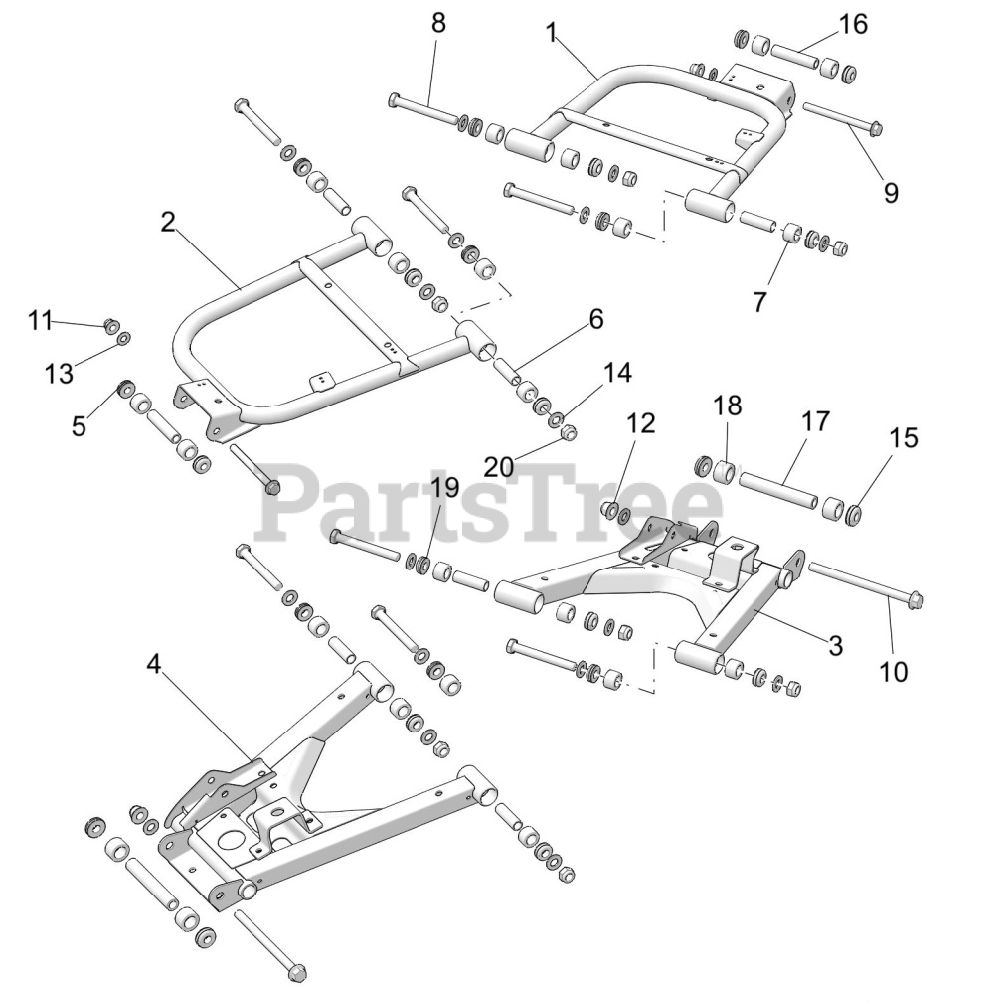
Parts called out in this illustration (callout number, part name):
1	WELD-CONTROL ARM, RR, UPR, LH, BLK
2	WELD-CONTROL ARM-RR-UPR-LH-BLK
3	WELD-CONTROL ARM-RR-UPR-RH-BLK
4	WELD-CONTROL ARM-RR-LWR-LH-BLK
5	WELD-CONTROL ARM-RR-LWR-RH-BLK
6	ASM-PIVOT CAP- SEALED- M10
6	SHAFT-PIVOT-SHORT-M12
8	BUSHING-STANDARD-SUSP-M10
9	SCR-HH-M12X1.75X100 10.9 ZPC
10	SCR-HXFL-M10X1.25X115 10.9 SPC
11	SCR-HXFL-M12X1.5X170 10.9 ZOD
12	NUT-M10X1.25-FLG-NYLOC-OLIVE D
13	NUT-M12X1.5-FLG-NYLOC-OLIVE D
14	WASHER-3/8 FW
15	WSHR-13.0X24.0X2.5 ZPC
16	ASM-PIVOT CAP-SEALED M12
17	SHAFT-PIVOT-SHORT-M10
18	SHAFT-PIVOT-LONG-M12
19	BUSHING-STANDARD-SUSP-M12
20	ASM-PIVOT CAP-SEALED-M12
